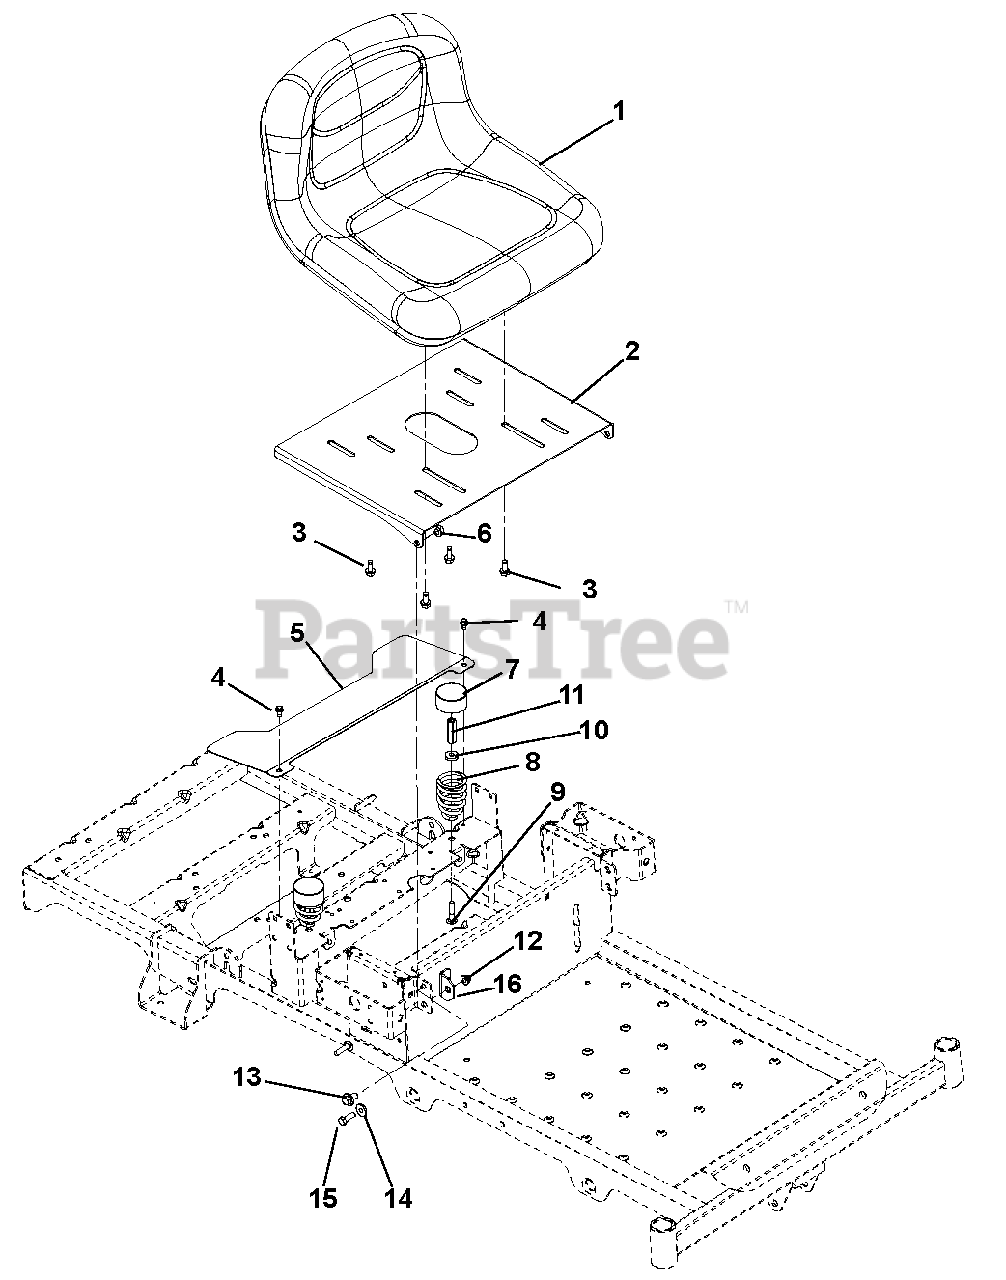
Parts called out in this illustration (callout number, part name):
1	Seat, 13 in Grey
2	Seat Plate
3	Bolt, Hex 5/16-18 x 3/4
4	Screw, Tapping .25-20 x .50 Hex Washer Head Thread
5	Guard, Fan
6	Nut, .38-16 Locking Top Flange
8	Spring, Seat
9	Bolt, Round Head Square Neck .31-18 x 1.50
10	Washer, Flat Steel .328 x .87 x .179
11	Nut, Coupling 5/16-18 x 1.75
12	Nut, 5/16-18 Flange Nyloc
13	Bolt, Shoulder .375-16 x .135
14	Bushing, Flange .325 x .499 x .26 x .88
15	Bolt, Hex .31-18 x 1.00
16	Bracket, Seat Stop
